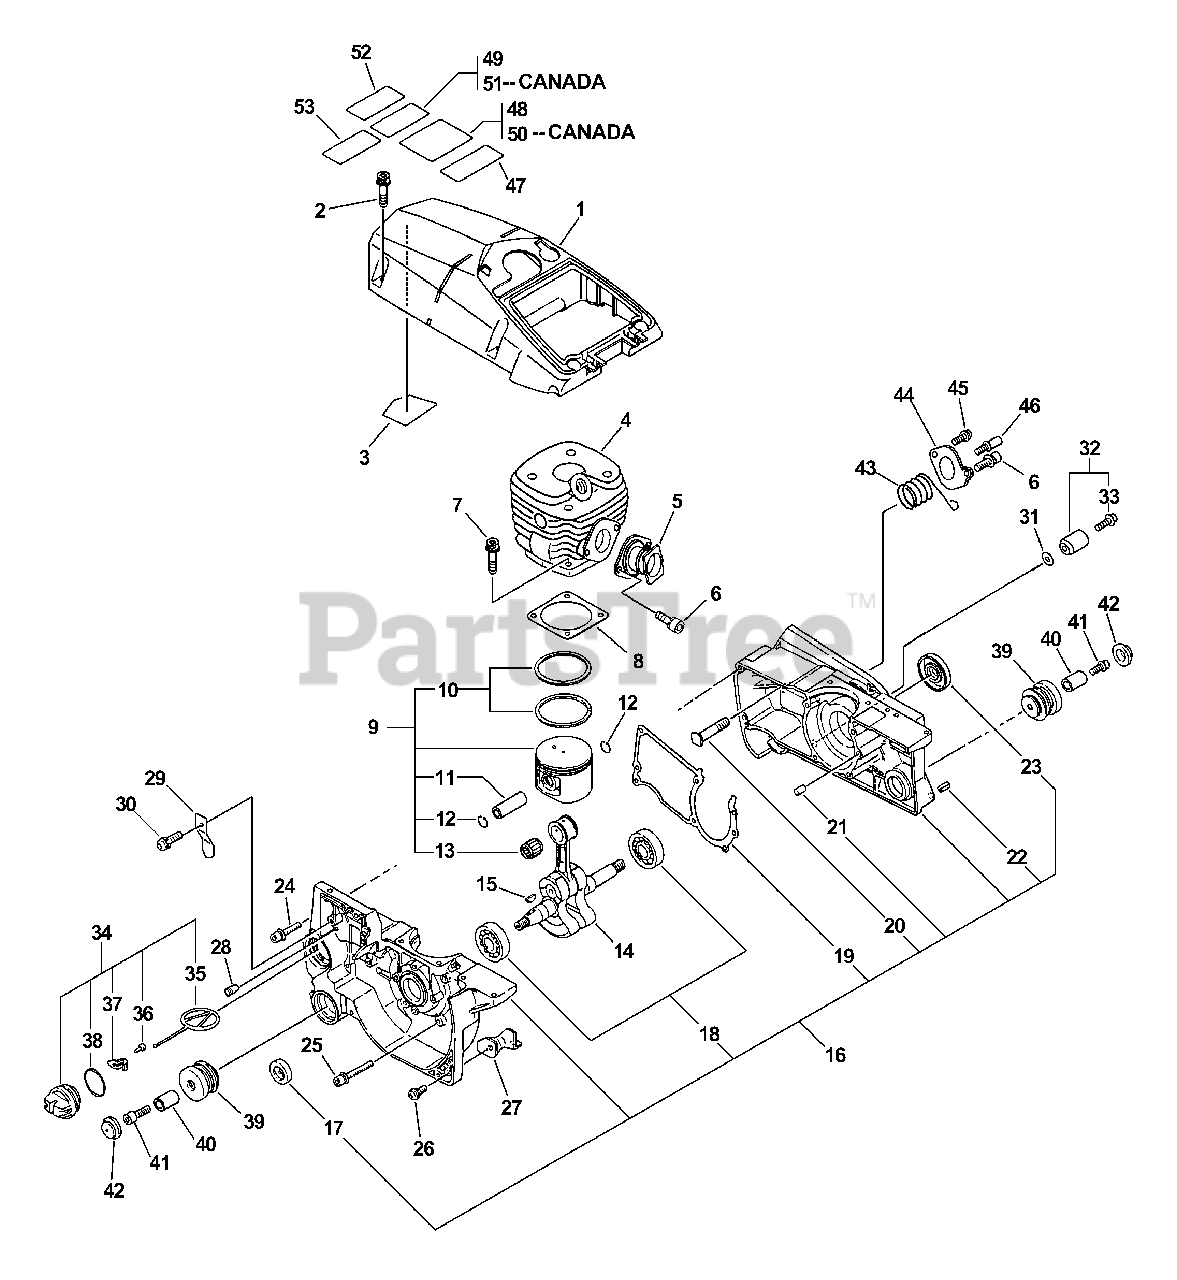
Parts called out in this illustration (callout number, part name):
1	COVER, ENGINE
2	BOLT 5×20
3	SHIELD, HEAT
4	CYLINDER
5	BELLOWS, INTAKE
6	BOLT 5×14
7	BOLT 5×25
8	GASKET, CYLINDER
9	PISTON KIT
10	RING, PISTON
11	PIN, PISTON 12
12	RING, SNAP
13	BEARING, NEEDLE
14	CRANKSHAFT ASSY
15	KEY, WOODRUFF
16	CRANKCASE KIT
17	SEAL, OIL
18	BEARING, BALL 6202
19	GASKET, CRANKCASE
20	STUD, GUIDE BAR 8
21	PIN, LOCATING 5×10
22	PIN, SPRING 5×10
23	SEAL, OIL
24	BOLT 5×20
25	BOLT M5×35
26	SCREW 5×14
27	CUSHION 5
28	VENT ASSY
29	PLATE, EYE
30	SCREW 4×8
31	WASHER, FLAT 5.5×10×0.8
32	CHAIN CATCHER KIT
33	SCREW 5×18
34	CAP ASSY, OIL
35	CONNECTOR, CAP L= 60 MM
36	SCREW, TAPPING 3×8
37	RETAINER, CONNECTOR
39	CUSHION
40	COLLAR 5
41	BOLT 5×25
42	CAP, CUSHION
43	SPRING, COMPRESSION
44	PLATE, EYE
45	BOLT 4×8
47	LABEL, KICK BACK WARNING
48	LABEL
49	LABEL, UL - KICK BACK
50	LABEL - BAR & CHAIN
51	LABEL, KICK BACK - FRENCH
52	LABEL, NOISE - ENGLISH/FRENCH
53	LABEL, KICK BACK
